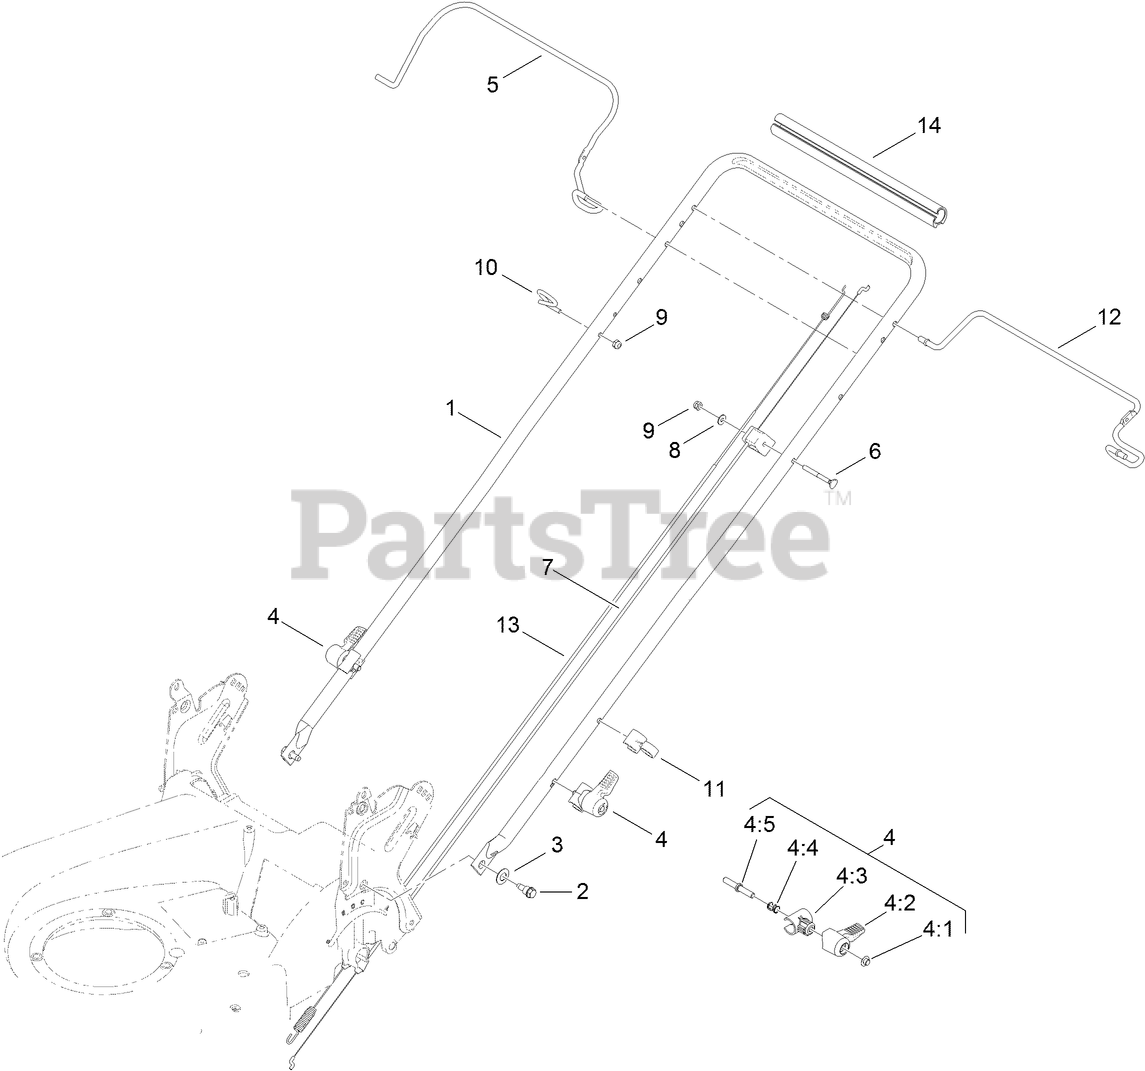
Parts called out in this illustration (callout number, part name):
2	BOLT-SHOULDER
3	WASHER-SPRING, CONICAL
4	QUICK RELEASE ASM
4:2	LEVER
4:3	ANCHOR-SPRING
4:4	SPRING-COMPRESSION
4:5	ROD-RELEASE
5	BAIL-BRAKE
6	SCREW-HANDLE
7	CABLE-BRAKE
8	WASHER-FLAT
9	NUT-LOCK, NI
10	GUIDE-ROPE
11	GUIDE-CABLE
12	BAIL-TRACTION
13	CABLE-TRACTION
14	GRIP-HANDLE, COMFORT
